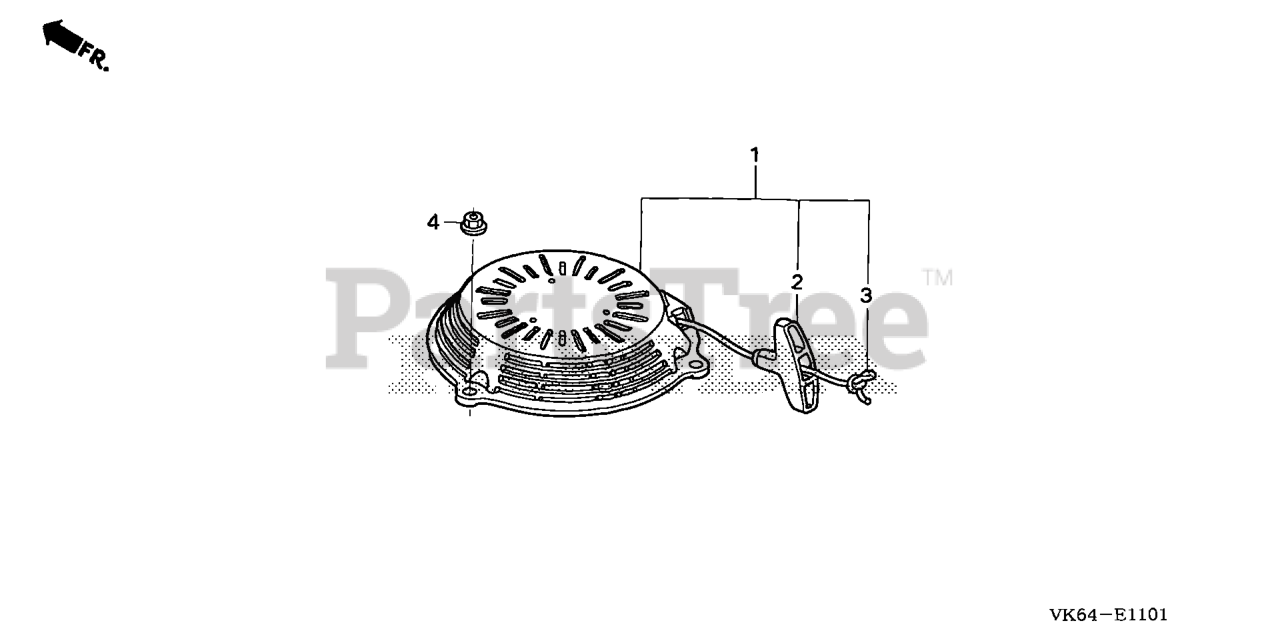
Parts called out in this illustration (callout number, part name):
1	STARTER ASSY., RECOIL *R280* (LONG ROPE) (POWER RED)
1	STARTER ASS*R280*
2	KNOB, RECOIL STARTER
3	ROPE, RECOIL STARTER (Honda Code 5580642). (#3.5X90")
3	ROPE, RECOIL STARTER (LONG TYPE)
4	NUT, FLANGE (6MM)
